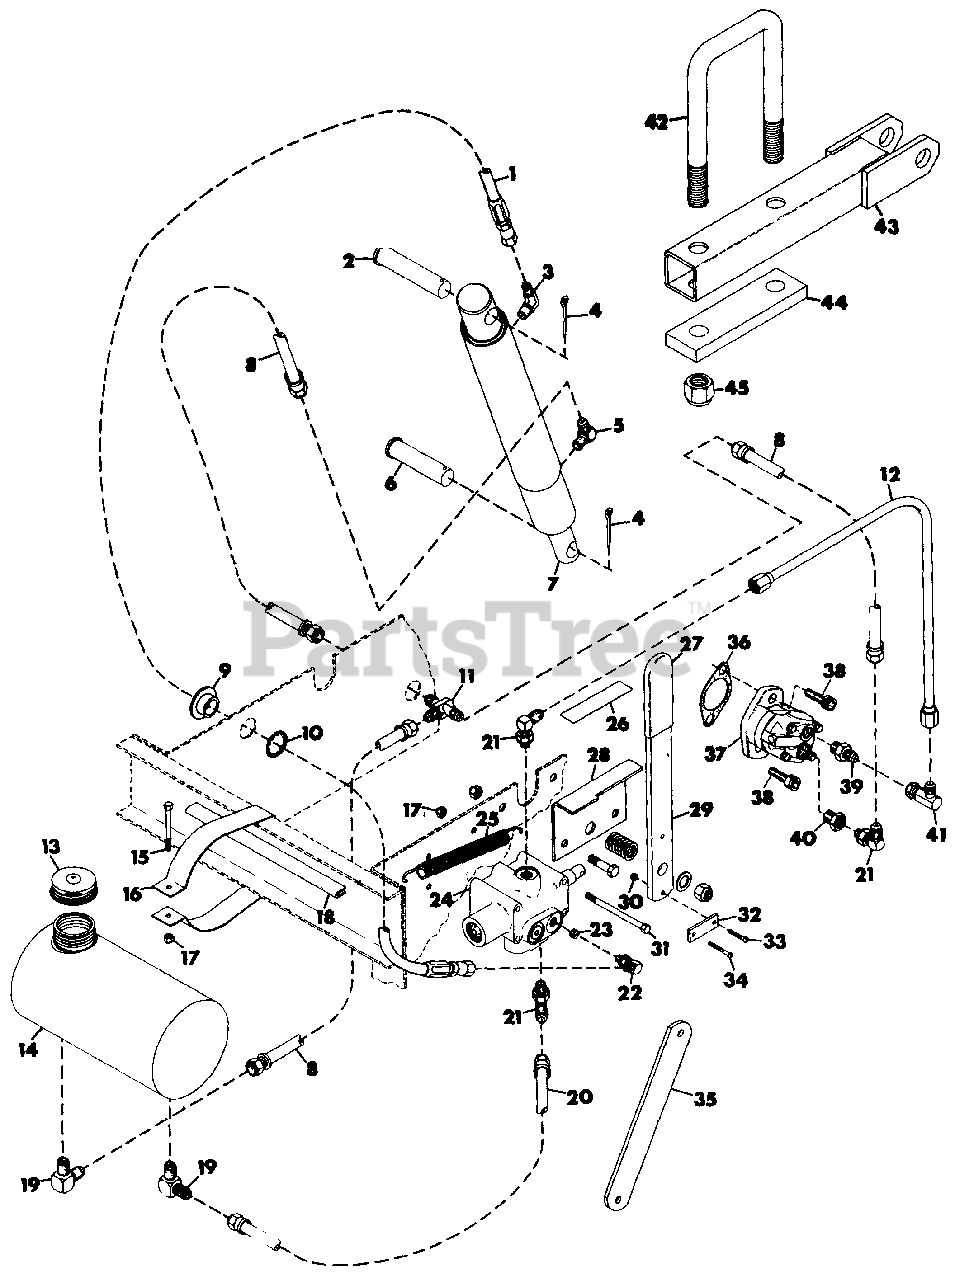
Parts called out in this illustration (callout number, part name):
1	HOSE, HYDRAULIC
2	PIN, CLEVIS
3	ADAPTOR
4	PIN, COTTER .125X1.25
5	ADAPTOR, HYDRAULIC
6	PIN, CLEVIS
7	CYLINDER, HYDRAULIC
8	HOSE, HYDRAULIC
9	BUSHING, NYLON .76X1X.6 FLG.
10	RING, RETAINING INTERNAL TOOTH
11	ADAPTOR, TEE
12	LINE, HYDRAULIC PUMP TO VALVE
13	CAP, HYDRAULIC TANK
14	TANK, HYDRAULIC
15	BOLT, HEX 1/4-20X1.75
16	STRAP, HYDRAULIC TANK
17	NUT, LOCK 1/4-20
18	MOULDING, TANK
19	ADAPTOR
20	ASSEMBLY, HOSE VALVE TO TANK
21	ADAPTOR
22	ADAPTOR
23	PLATE, FLOW RESTRICTION
24	VALVE, CONTROL
25	SPRING, EXTENSION 5.5X.5X20 RATE
26	DECAL, HYDRAULIC LIFT
27	GRIP, HANDLE
28	BRACKET, LIFT
29	LEVER, LIFT
30	NUT, LOCK 10-24
31	BOLT, HEX 1/4-20X2.75
32	STRAP, VALVE
33	SCREW, MACHINE 10-24X.75
34	SCREW, MACHINE 10-24X1.00
35	BAR, DECK LIFT
36	GASKET, COVER
37	PUMP, HYDRAULIC
38	SCREW, CAP 3/8-16 HEX SOCKET HEAD
39	ADAPTOR
40	BUSHING
41	ADAPTOR
42	U-BOLT
43	ARM, LIFT
44	PLATE, AXLE
45	NUT, LOCK 5/8-18
